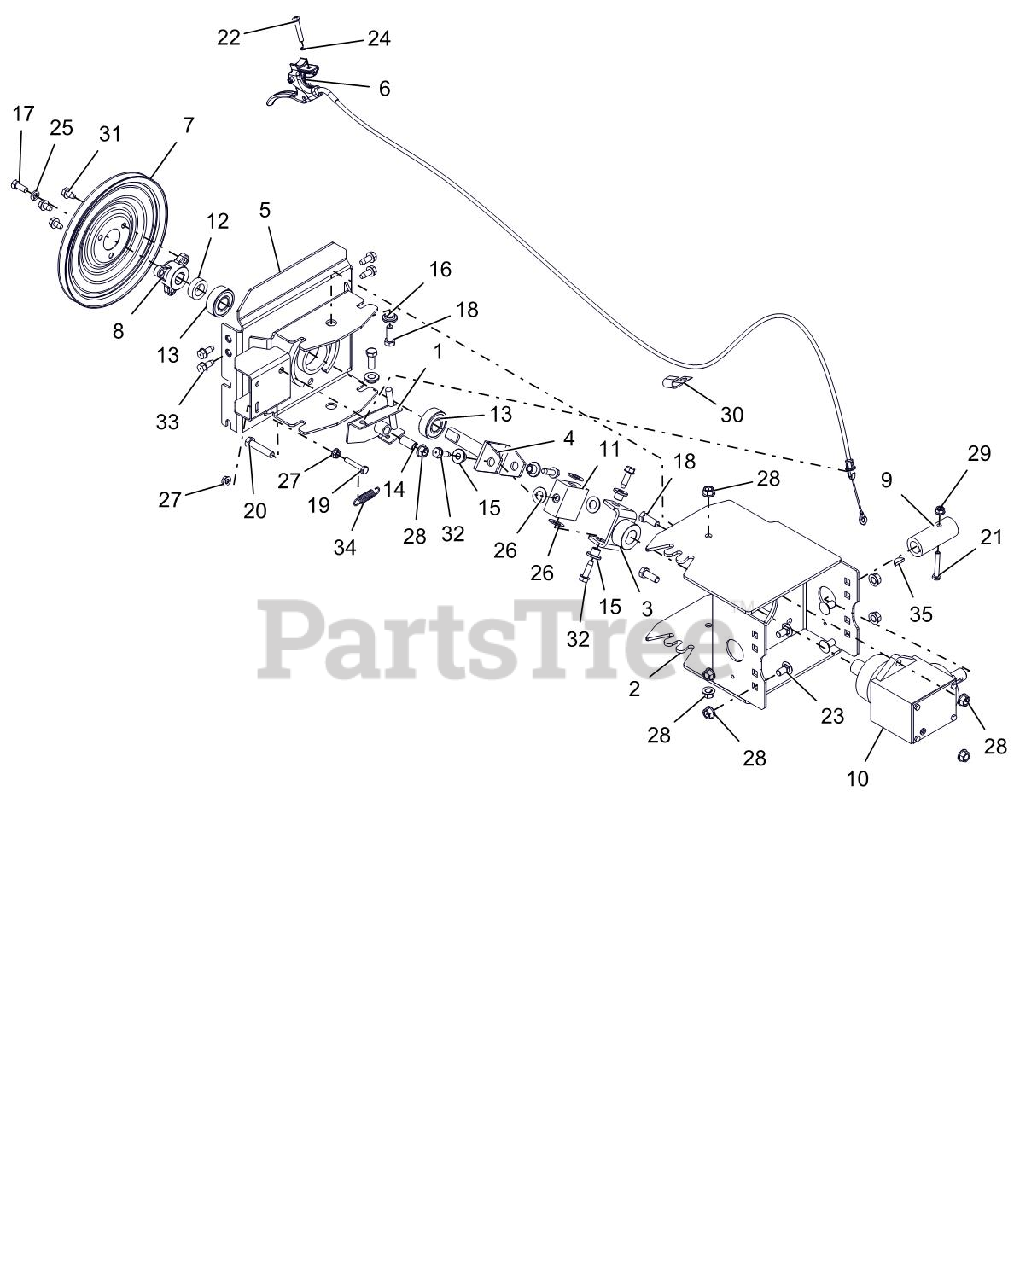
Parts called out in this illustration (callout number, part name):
1	ARM, PIVOT LOCK
2	ADAPTER, BROOM FRAME
3	JOINT,UNIVERSAL
4	JOINT,UNIVERSAL
5	ADAPTER, FRAME-20000 SERIES
6	CABLE, REMOTE BRUSH LOCK
7	PULLEY,SPIN FORM SINGLE GROOVE
8	PULLEY HUB, BOLT-ON D-BORE .75
9	HUB, COUPLING
10	GEAR BOX ASSEMBLY
11	BLOCK, UNIVERSAL
12	SPACER .755X1.250X.370
13	BRG-BALL .750X1.781X.61
14	BSHG-SLV .385X.500X1.045
15	BSHG-FLG .325X.500X.513X.875
16	BSHG-FLG .406X.88X.270X.140
17	BLT-HEX .31-24X.75 YWZC GR5
18	BLT-HEX .38-16X1.00 GR5 YWZC
19	BLT-HEX .25-20X1.50 GR5 YWZC
20	BLT-HEX .38-16X1.75 GR5 YWZC
21	BLT-HEX .25-20X1.75 GR5 YWZC
22	SCR-MCH .25-20X1.50 OVAL HD
23	BLT-RDHDSQNK .38-16X.75 G5YZ
24	WSHR-LK-INT .250 TH TYA
25	WSHR-LK .312X.097 HVY YWZC
26	WSHR-HDND-STL-THR.515X.97X.062
27	NUT-SPNLK-FLG .25-20 YWZC
28	NUT-LK-TOP-FLG .38-16 YWZC
29	NUT-LK-TOP-FLG .25-20 YWZC
31	SCR-TAP .31-18X.50 HWH TR YWZ
32	SCR-TAP .31-18X1.00 HWH TR YZ
33	SCR-TAP .31-18X.75 HWH TR YWZ
34	SG-TENS .06X.46X2.00
35	KEY-WDRF .188X.75X.313 SAE 9
